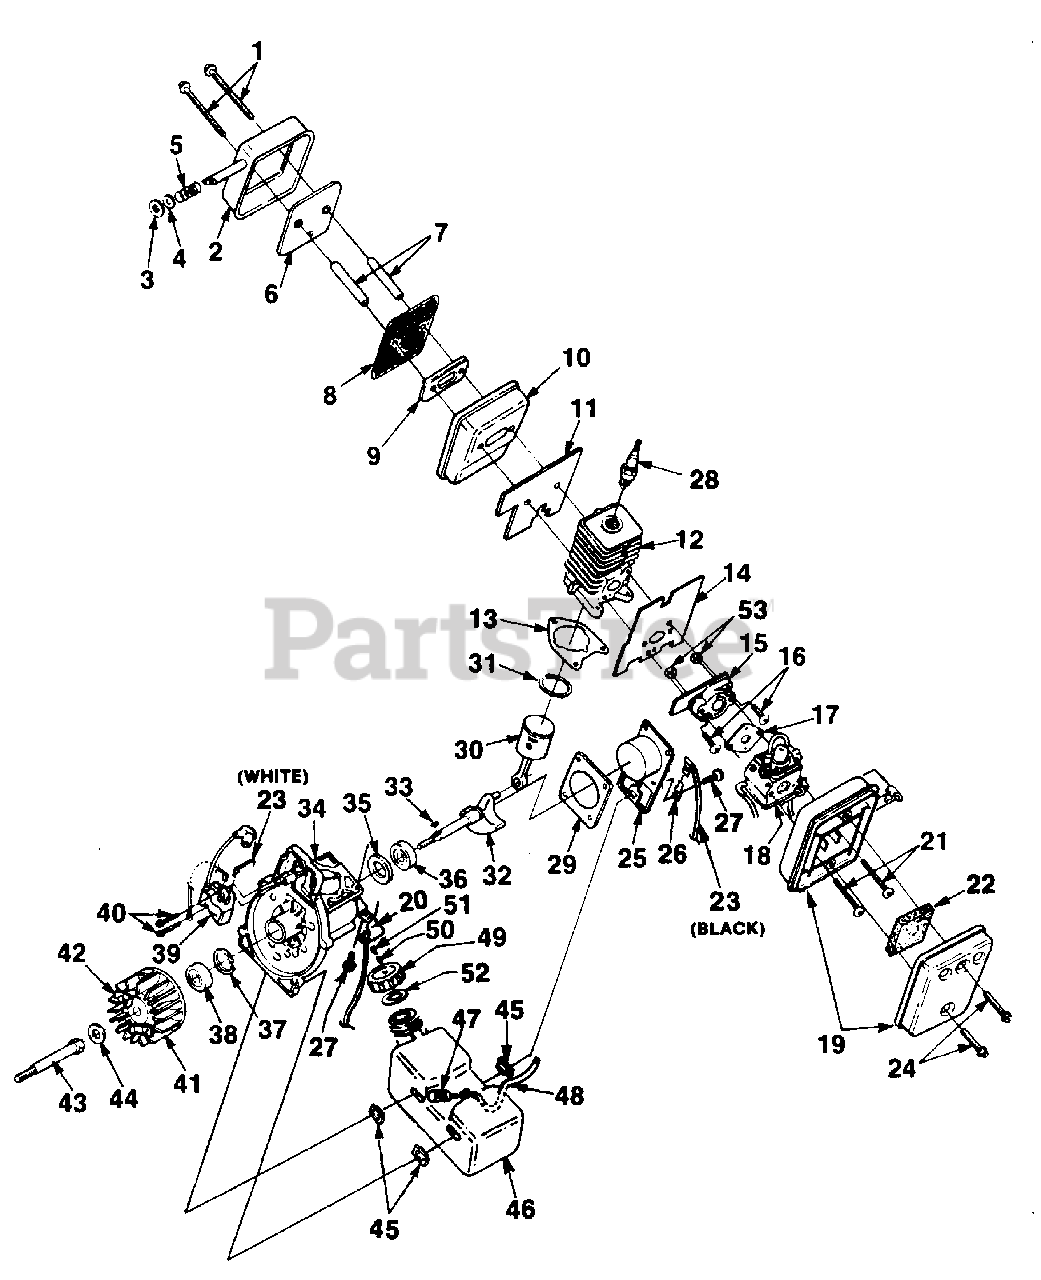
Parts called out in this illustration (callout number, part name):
1	SCREW- Sems hex hd. (10-24 x 2 1/2")
2	COVER- Muffler
3	WASHER- Insulating
4	WASHER- Flat
5	SPRING- Compression
6	DEFLECTOR- Muffler
7	SPACER- Muffler
8	SCREEN- Spark Arrestor
9	PLATE- Reinforcing
10	BODY- Muffler
11	GASKET- Muffler
12	CYLINDER
13	GASKET
14	GASKET- Heat dam
15	HEAT DAM
16	SCREW
17	GASKET- Carburetor
18	CARBURETOR (WT-150) Walbro
19	BOX- Air filter
20	CABLE- Bracket
21	SCREW- Thd. forming (10-24 x 2 1/4")
22	FILTER- Air
23	LEAD & TERMINAL
24	SCREW- Thd. forming (8-16 x 3/4")
25	COVER- Crankcase
26	TERMINAL- Male tab
27	SCREW- Taptite (#10-24 x 3/4")
28	SPARK PLUG
29	GASKET- Crankcase
30	PISTON & ROD ASSY.
31	RING- Piston
32	CRANKSHAFT
33	KEY- Woodruff
34	CRANKCASE ASSY.
35	SEAL- Shaft
36	BEARING- Ball
37	RING- Retaining
38	BEARING- Ball
39	MODULE- Ignition (Sawafugi)
40	SCREW-Thd. forming (8-32 x 1")
41	ROTOR & STARTER PAWL Sawafugi (Black)
42	STARTER PAWL KIT
43	ADAPTER- Fan
44	WASHER- Flat (5/16")
45	BUMPER- Rubber
46	TANK- Fuel
47	FILTER- Fuel
48	TUBING- Rubber
49	FUEL CAP ASSY.
50	VALVE- Duck Bill
51	FILTER
52	GASKET- Fuel cap
